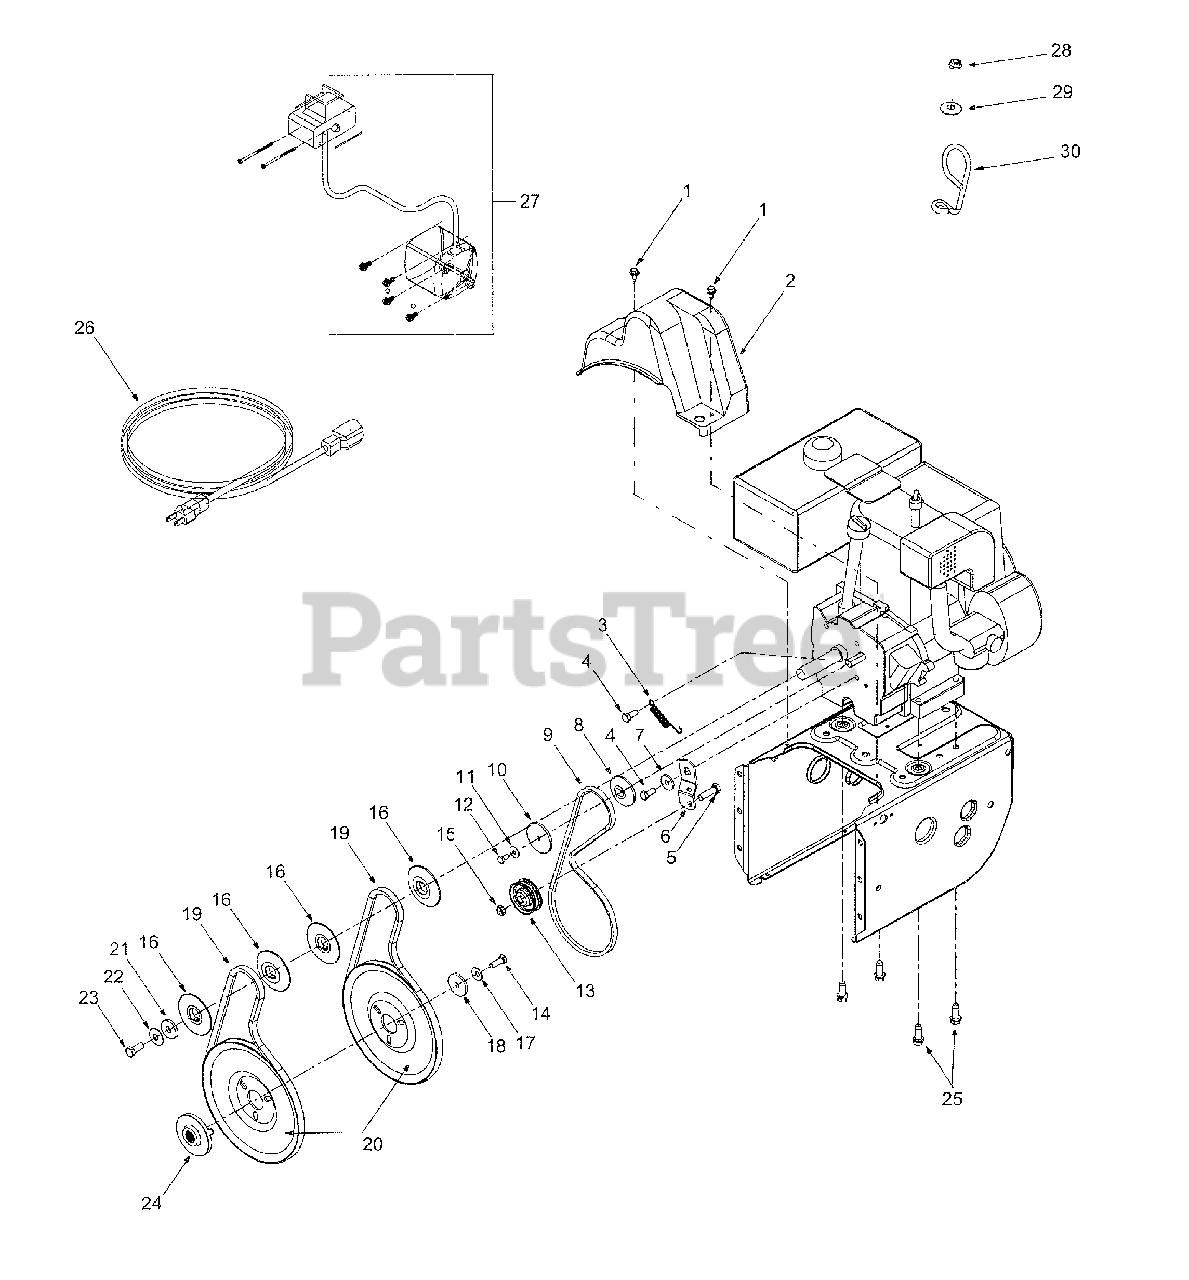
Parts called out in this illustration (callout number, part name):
1	Hex Washer Screw 1/4-20 x .625
2	Belt Cover
3	Extension Spring
4	Hex Screw 5/16-24 x .75
5	Hex Cap Screw 3/8-16 x 1.25
8	Pulley Half
9	V-Belt
10	Pulley Half
11	Bell Washer
12	Hex Cap Screw 1/4-28 x .50
13	Flat Idler
14	Lock Hex Cap Screw 5/16-24
15	Lock Jam Nut 3/8-16
16	Pulley Half
17	Bell Washer
18	Flat Washer
19	Belt
20	Auger Pulley
21	Flat Washer 3/8 x 1.25 OD
22	Bell Washer
23	Hex Cap Screw 3/8-24
24	Adapter Pulley
25	Hex Screw 3/8-16 x 1.0
26	Extension Cord
27	Electric Start Kit
28	Lock Nut, 1/4-20
29	Flat Washer, .28 x .74 x .063
30	Cable Guide
